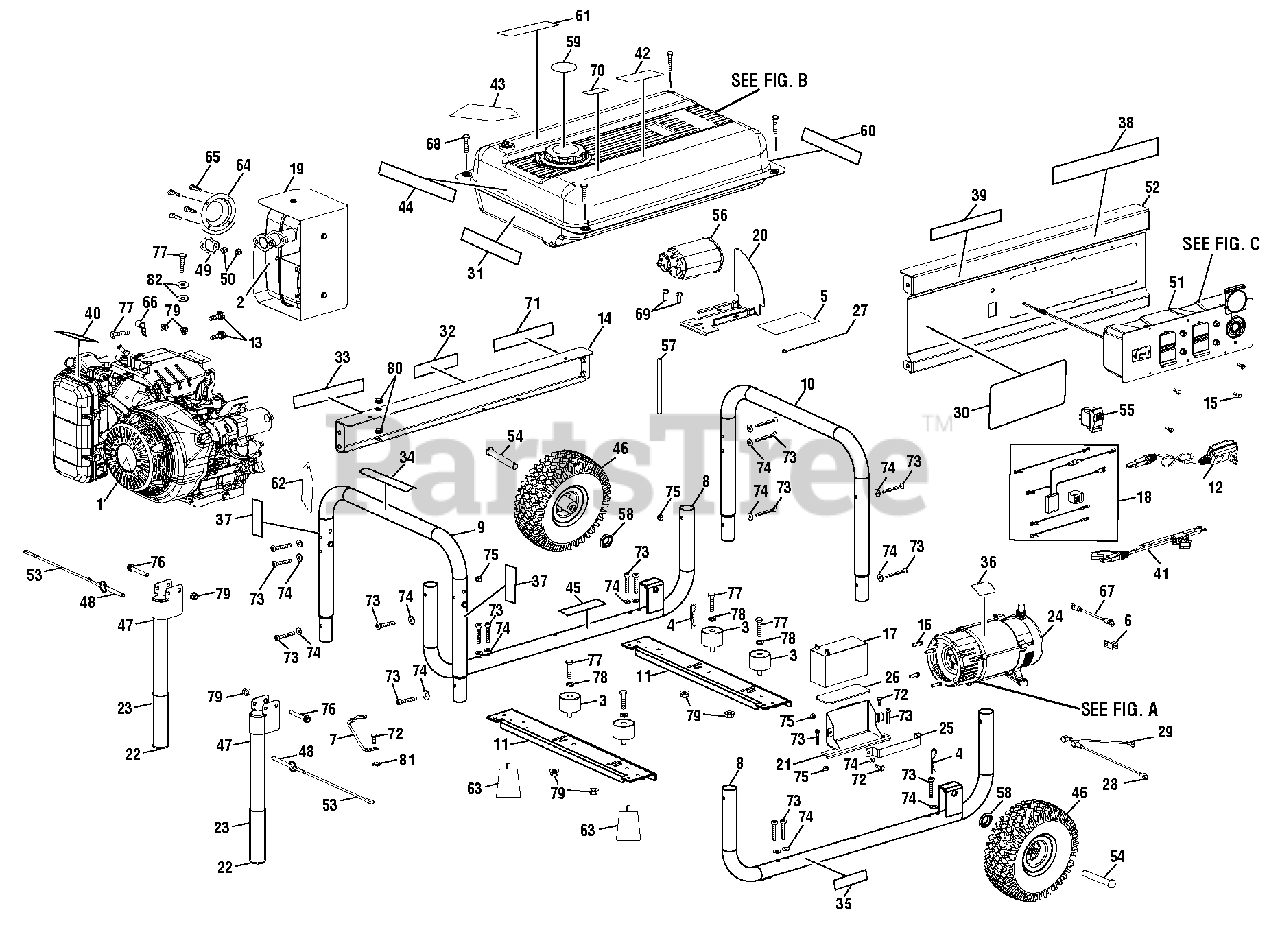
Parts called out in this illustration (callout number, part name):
1	Engine (Honda)
4	Hitch Pin
5	Rubber Sheet
6	Ground Lug
7	Ground Wire Assembly
8	Lower Frame Assembly
9	Tube Assembly (Left)
10	Tube Assembly (Right)
11	Cross Brace
12	Battery Charger
13	Bolt (5/16-24 x 5/8 in.)
14	Back Panel
15	Screw (6-20 x 3/8 in.)
16	Bolt (3/8-16 x1.25 in.)
17	Battery
18	Wire Harness
19	Heat Shield
20	Bracket (Carbon Canister)
21	Battery Box Gasket
22	Plastic Cap
23	Handle Grip
24	Generator Head w/AVR
25	Battery Hold Down Bracket
26	Gasket (Battery Hold Down Bracket)
28	Battery Cable (Red)
29	Battery Cable (Black)
30	Logo Label
31	Electric Start Label
32	Hot Surface Label
33	Danger Label
34	Fire Danger Label
35	Engine Lubricant Label
36	Data Plate Label
37	Locking Pin Label
38	Honda Label
39	Electric Start Label
40	Choke Label
41	Pigtail (DC)
42	CPSC Label
43	Danger Hang Tag
44	Inquires Label
45	Combustion Warning Label
47	Handle Assembly
48	Release Pin (5/16 x 2 in.)
49	Exhaust Gasket
51	Panel Assembly
52	Front Panel
55	Start Switch w/Lock
56	Carbon Canister Assembly
57	Purge Hose
58	Washer (1/2 in.)
59	Fuel Stabilizer Label
60	Ground Warning Label
61	Fuel Warning Label
63	Foot Assembly
64	Spark Arrestor
65	Screw (8-32 x 3/8 in., Pan Hd.)
66	J-Clamp (1/2 in.)
67	Bonding Wire
68	Screw (1/4-14 x 1-1/4 in.)
69	Screw (#10-16 x 3/4 in.)
70	E85 Label
71	Fire Distance Label
72	Screw (M6 x 16 mm, Hex Hd.)
73	Screw (M6 x 50 mm, T30, Pan Hd.)
74	Washer (M6)
75	Lock Nut (M6)
76	Bolt (M8 x 55 mm, Hex Hd.)
77	Bolt (M8 x 35 mm, Hex Hd.)
78	Washer (M8)
79	Flange Nut (M8 x 1.25)
80	Hose Protector
81	Star Washer (M6)
82	Washer (5/16 in)
